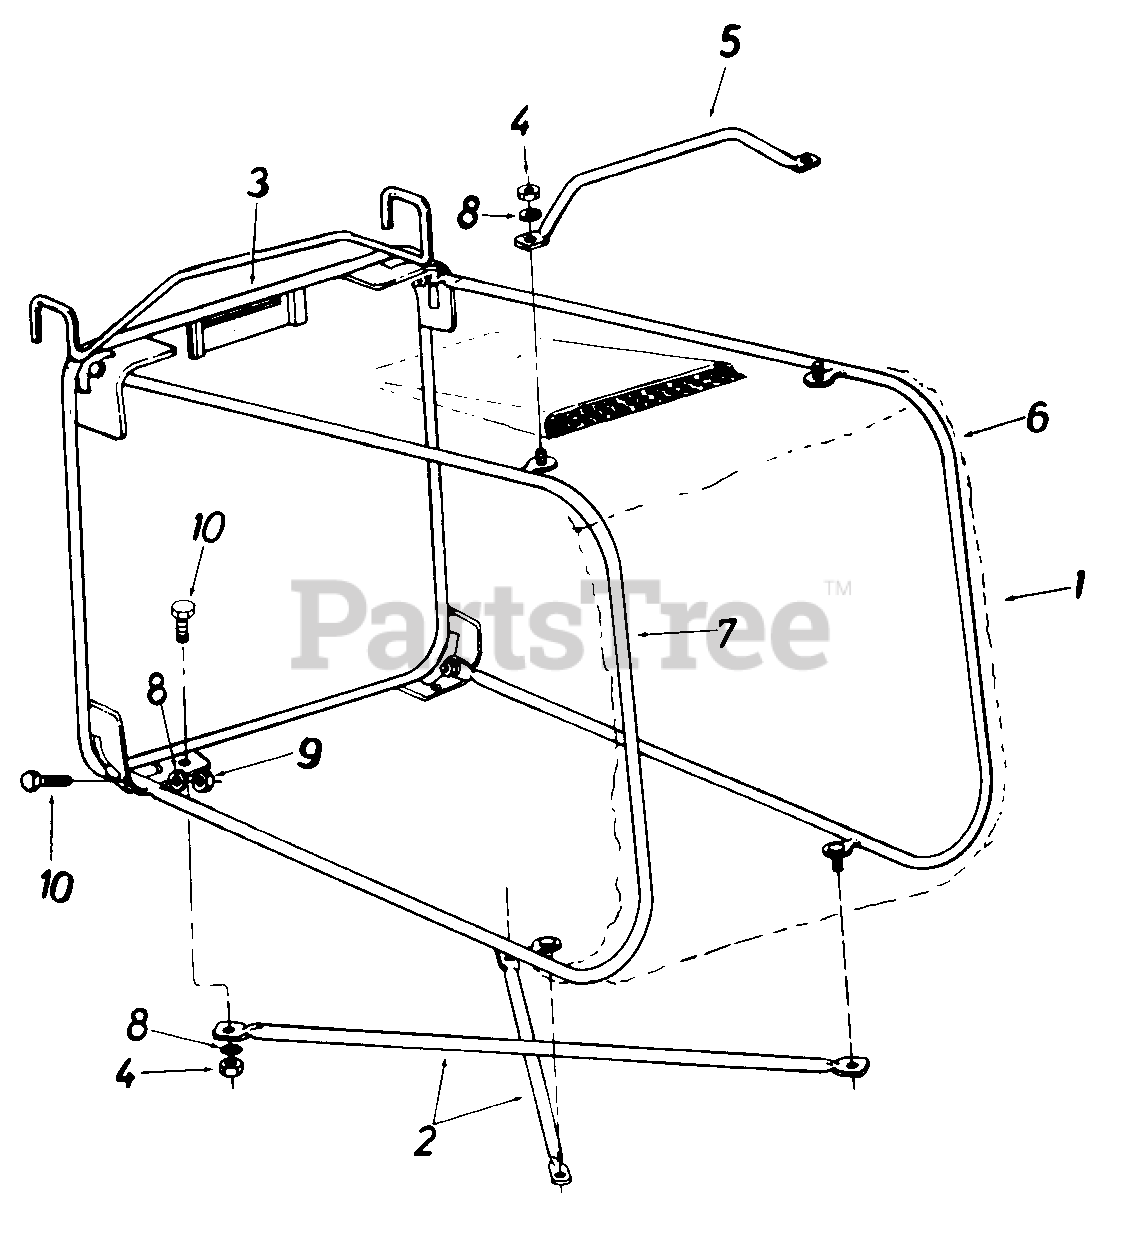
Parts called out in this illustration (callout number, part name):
1	Grass Catcher Bag
2	Bottom Cross Brace
3	Grass Catcher Frame Ass'y.
4	Hex Cent. L-Nut 1/4-20 Thd.
5	Grass Catcher Handle
9	Hex Cent. L.-Nut 1/4-20 Thd.
10	Hex Bolt 1/4-20 x .62" Lg.*
